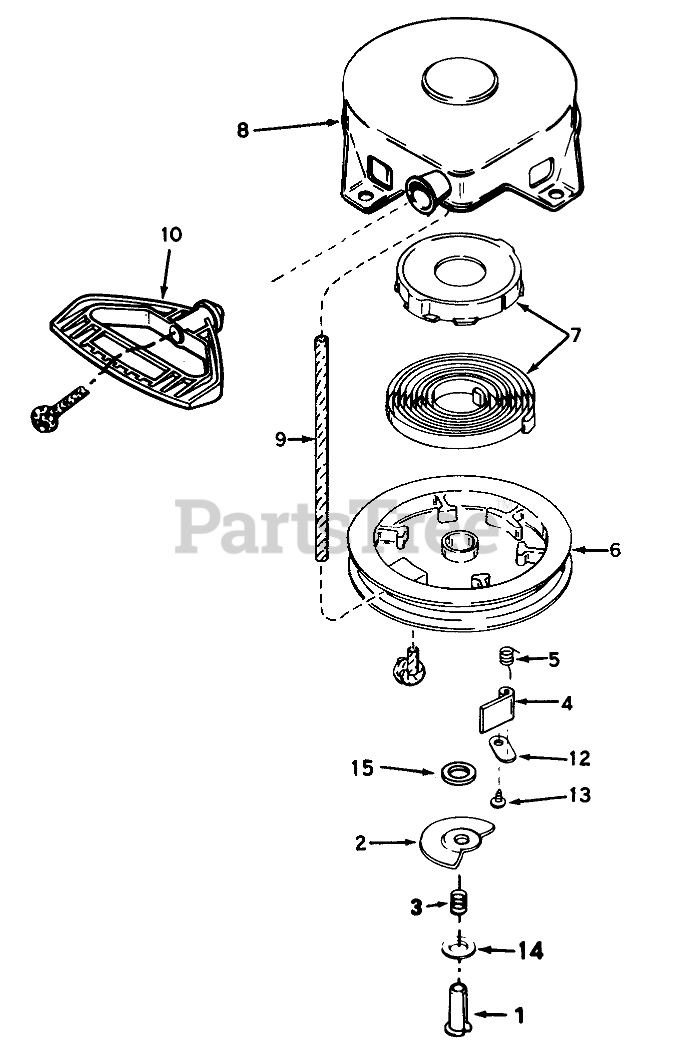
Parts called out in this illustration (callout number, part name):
1	Pin-Spring (Incl. Ref. #15)
3	Brake Spring
4	Dog-Starter
5	Spring-Dog
7	Spring & Keeper Assy
8	Housing-Starter
9	Rope-Starter
10	Handle-Starter, Mitten Grip
12	Retainer-Dog
